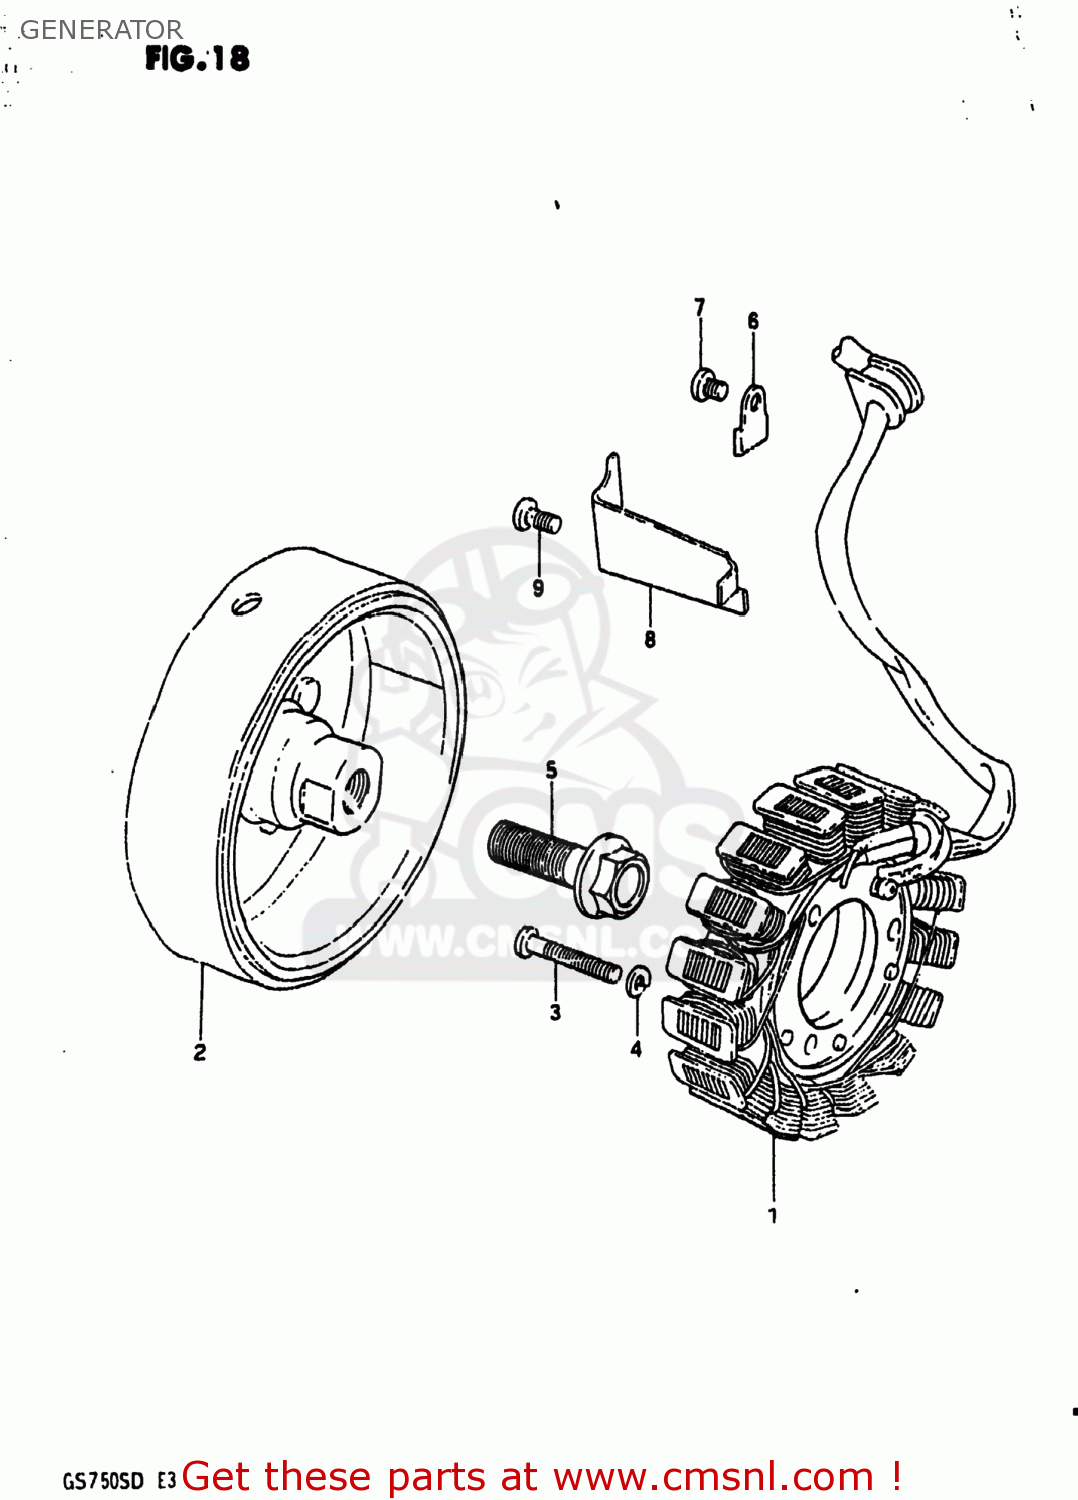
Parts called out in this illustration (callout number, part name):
1	STARTER ASSY
2	ROTOR ASSEMBLY
3	SCREW
4	LOCK WASHER
5	BOLT(12X40)
6	CLAMP,GENERATOR LEAD WIRE
7	SCREW
8	CLAMP,GENERATOR LEAD WIRE
9	SCREW
